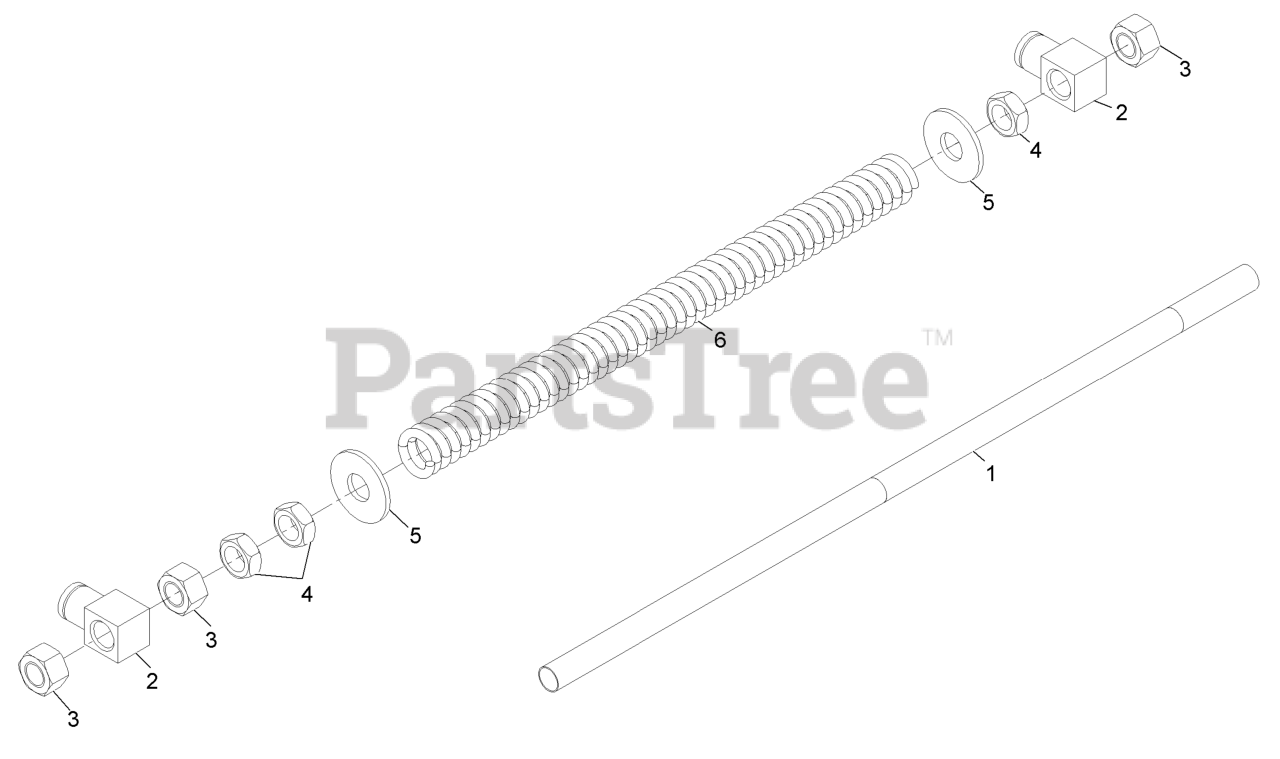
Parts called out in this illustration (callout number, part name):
1	ROD-LIFT, DECK
2	SWIVEL-DECK MOUNT, REAR
3	NUT-HEX
4	NUT-JAM
5	WASHER-FLAT
6	SPRING-SUPPORT, DECK
